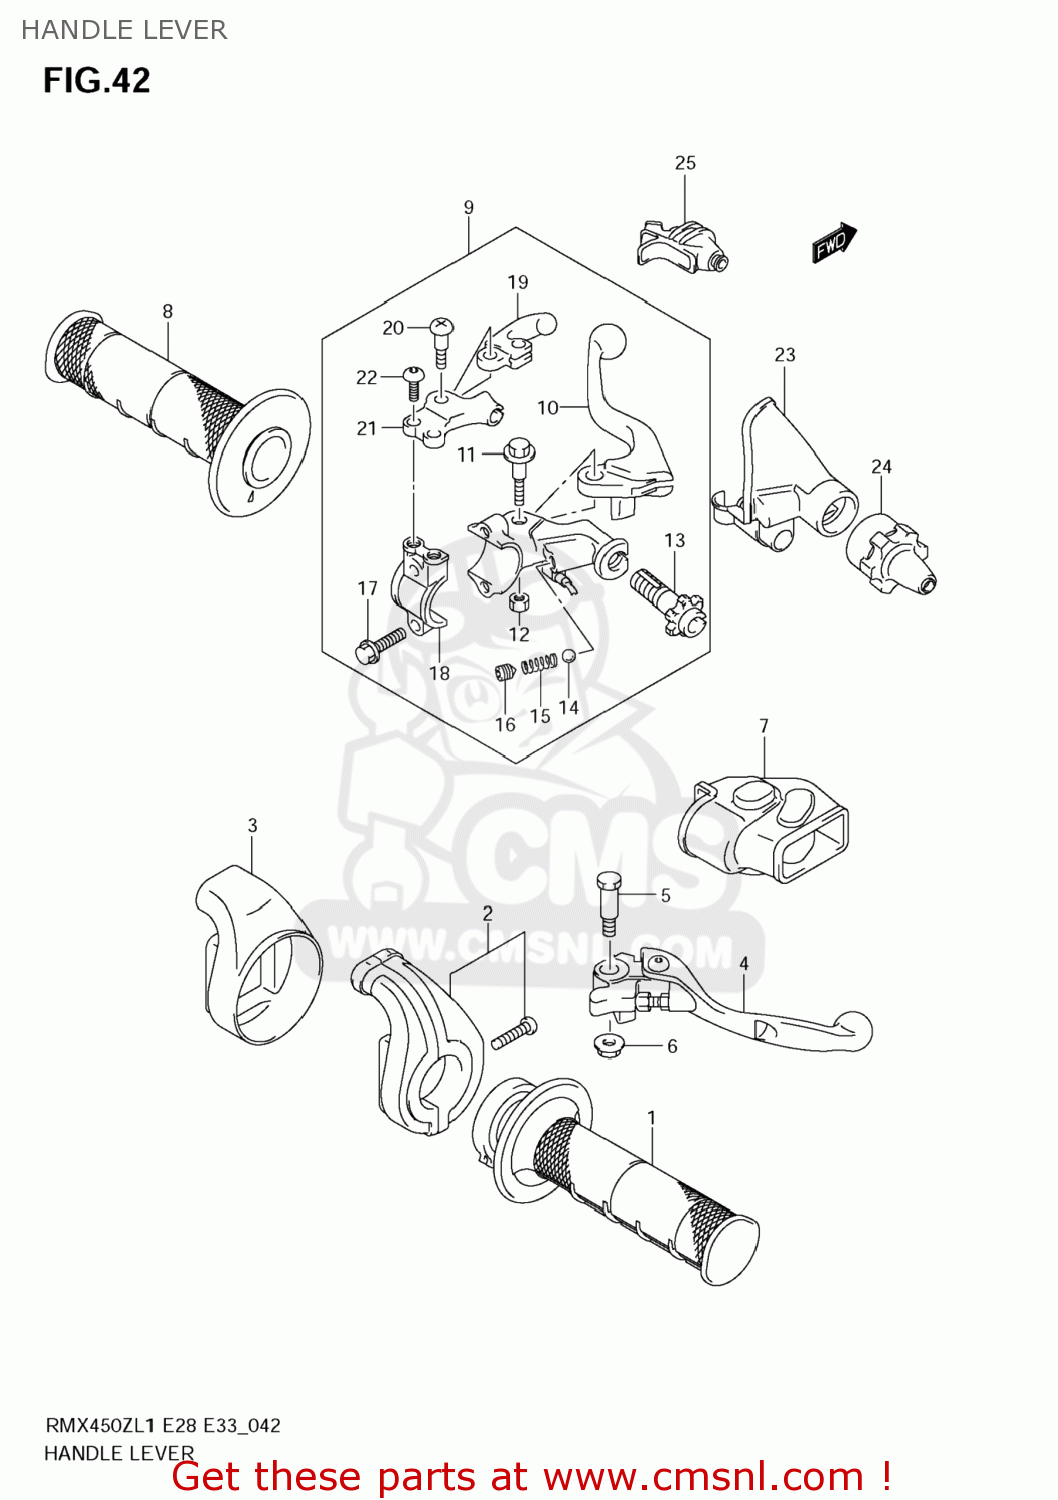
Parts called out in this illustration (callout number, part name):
1	GRIP,THROTTLE
2	CASE ASSY,THROTTLE
3	COVER,THROTTLE CASE
4	LEVER ASSY,BRAKE
5	BOLT,BRAKE LEVER
6	NUT
7	COVER,BRAKE LEVER
8	GRIP,L
9	LEVER ASSY,CLUTCH
10	LEVER,CLUTCH
11	BOLT
12	NUT
13	ADJUSTER,CABLE
14	BALL
15	SPRING
16	SCREW(6X8)
17	BOLT,BRACKET
18	HOLDER,CLUTCH LEVER
19	LEVER,HOT STARTER
20	BOLT,HOT STARTER LEVER
21	HOLDER,HOT STARTER LEVER
22	SCREW(5X12)
23	COVER,CLUTCH LEVER
24	COVER,CLUTCH ADJUSTER
25	COVER,HOT STARTER LEVER
